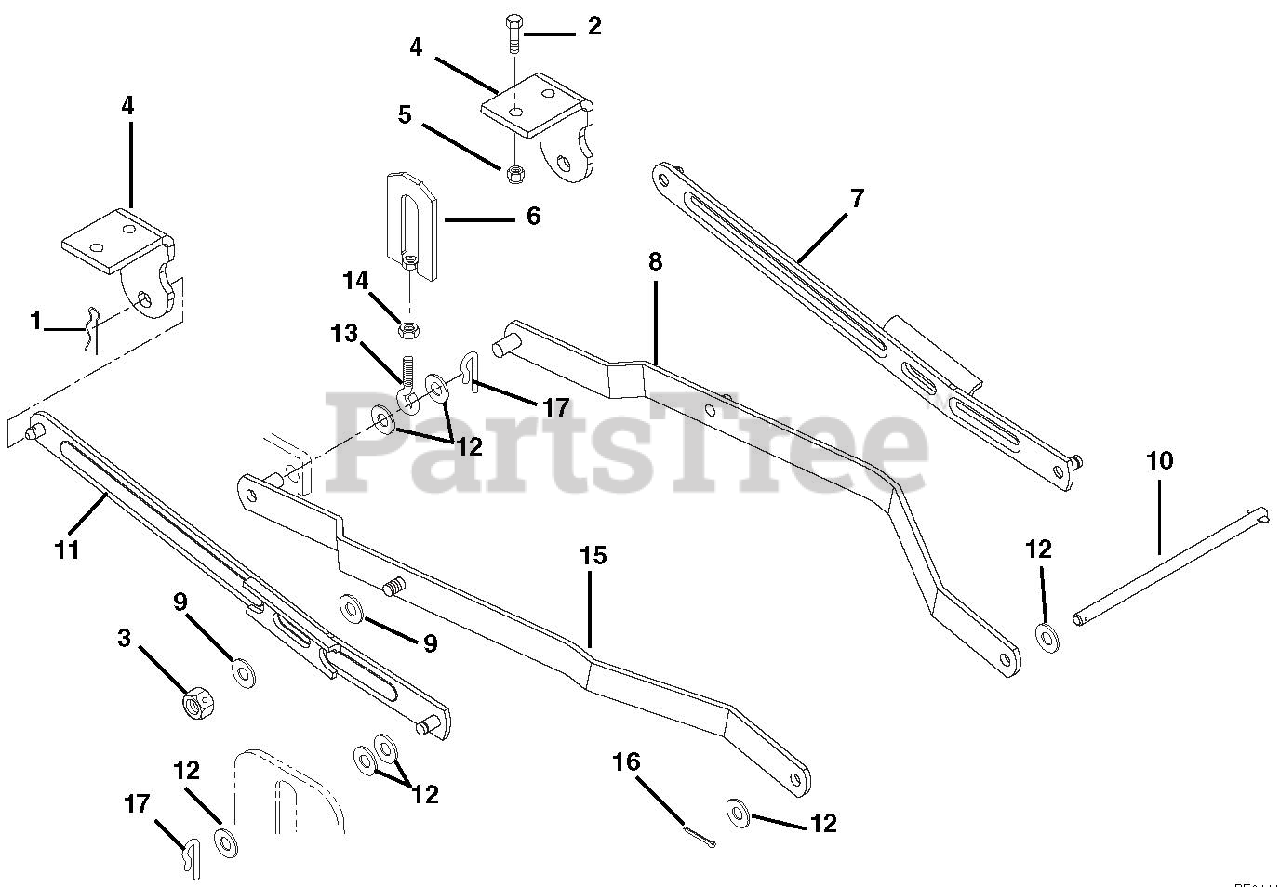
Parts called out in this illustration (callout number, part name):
1	PIN-HAIR-EXT .12X.31X2.37 YWZC
2	@BLT-HEX .38-16X.75 GR5 YWZC
3	@NUT-LK-CTR .62-11 YWZC
4	REAR HANGER
5	@NUT-LK-CTR .38-16 YWZC
6	LINK, ADJUSTMENT
7	HANGER, REAR LH
8	ARM, LIFT LH
9	@WSHR-FL-STL.656X1.31X.095 YWZ
11	HANGER, REAR RH
12	WSHR-FL-STL .531X1.250X.10 YWZ
13	BLT-EYE .375-16X2.50 YWZC
14	NUT-HEX-JAM .375-16 YWZC
15	ARM, LIFT RH
16	@PIN-CTR .12X1.00 EXTPRSQCT YZ
17	CLIP, SPRING
